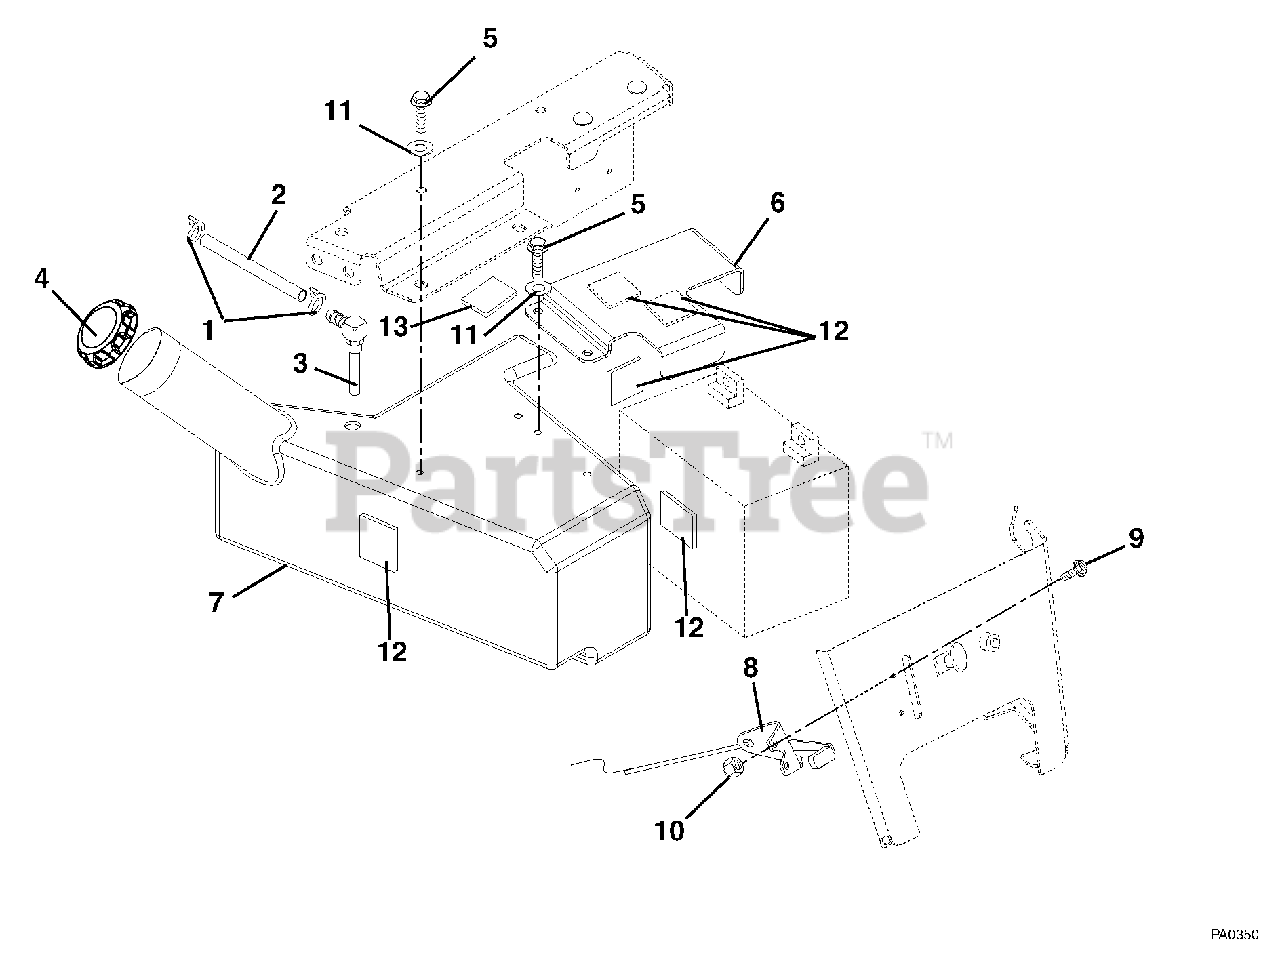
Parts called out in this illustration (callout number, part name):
1	Clamp, Hose Wire .490/.510 x .116
2	Gas Line, Bulk 1/4" I.D.
3	Fitting, Tank
4	Fuel Cap
5	Bolt, Serrated Hex Flange Washer Head .25-20 x .75
6	Bracket, Battery
7	Tank, Fuel
8	Cable, Throttle
9	Screw, Machine 10-24 x .50 Hex Washer Head
10	Nut, Locking Nylon 10-24 with Insertg
11	Washer-Locking .31 x .078 Regular
12	Pad, Foam
13	VHB Tape
